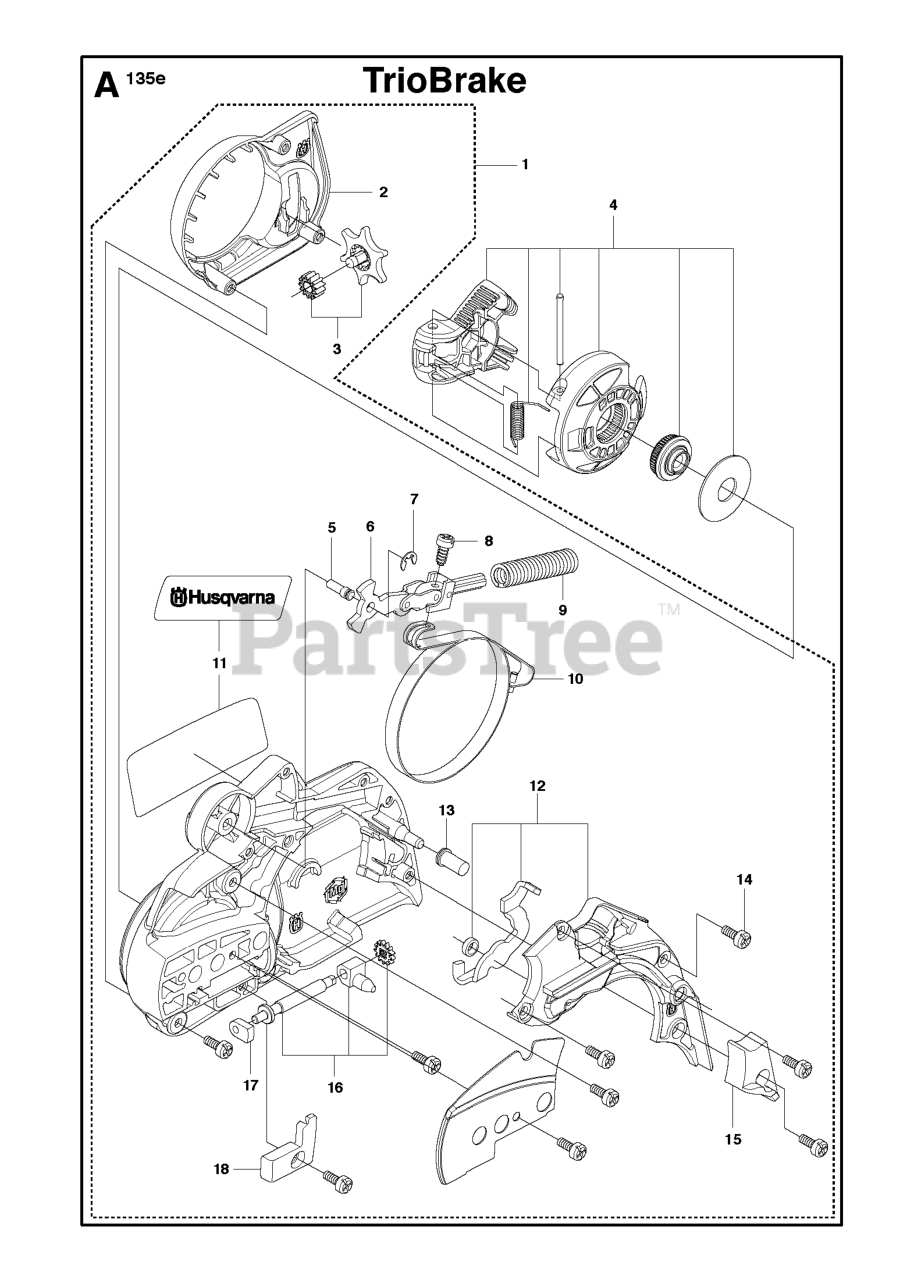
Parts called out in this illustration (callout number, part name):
1	CLUTCH COVER ASSY
2	HEAT SHIELD
3	CHAIN TENSIONER WHEEL, COMP.
4	KNOB, COMPLETE
9	BRAKE SPRING
10	BRAKE BAND ASSY
11	DECAL, CLUTCH HOUSING
15	WEAR PROTECTION
16	CHAIN TENSIONER SCREW
17	RP BEARING SLEEVE
